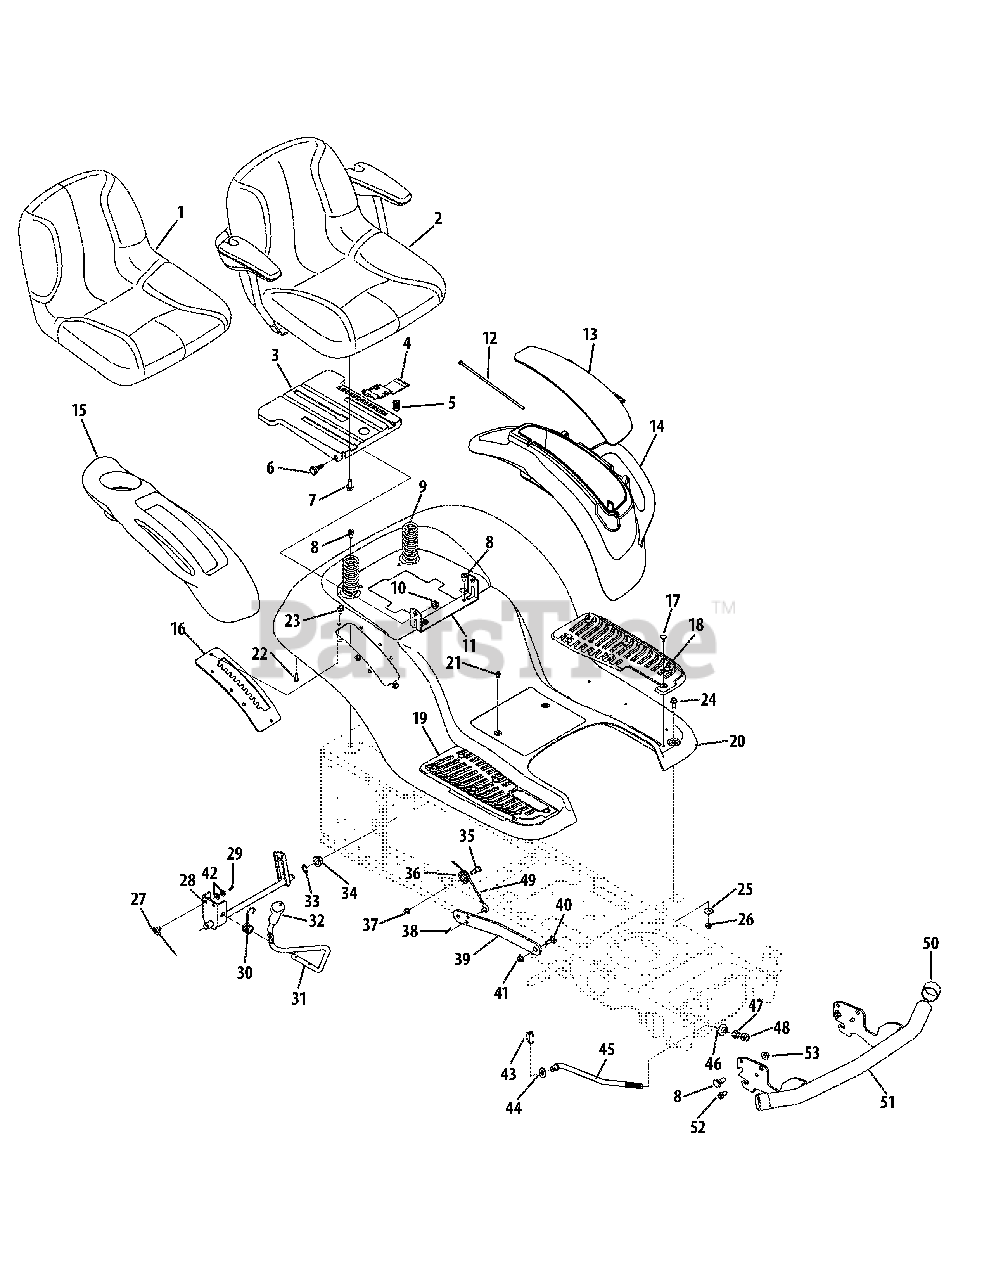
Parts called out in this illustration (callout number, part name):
1	High-Back Chair
2	High-Back Chair
2	Screw, 5.16-18 x .750
3	Seat Mounting Bracket
4	Seat Adjustment Lever
5	Compression Spring, .68 x 1.065 x .055
6	Shoulder Screw, 5.16-18 x .437 x .268
7	Hex Flange Bolt, 3.8-16 x .875
8	Hex Washer Screw, 5.16-18 x .750
9	Compression Spring, 1.71 x 3.735 x .238
10	Flange Lock Nut, 5.16-18
11	Seat Pivot Bracket
12	Door Pin LH Pod
13	Fender Cover Door
14	Fender Cover, LH
15	Fender Cover, RH
16	Lift Adjustment Bracket - Electric PTO
17	Ratchet Clip
18	Foot Pad, LH
19	Foot Pad, RH
21	Hex Washer Screw, 1.4-20 x .500
22	Hex Washer Screw, 1.4-15 x .750
23	Hex Washer Screw, 5.16-18 x .750
24	Hex Washer Screw, 5.16-18 x .750
25	Flat Washer, .344 x 1.0 x .063
26	Flange Lock Nut, 5.16-18
27	Lift Cable
28	Lift Shift Assembly SLTX1050
28	Lift Shift Assembly SLTX1054
29	Cotter Pin, .072 x 1.13
30	Torsion Spring
31	Lift Handle
32	Handle Grip
33	E-Type Ring
34	Hex Flange Bearing
35	Shoulder Screw, 5.16-18 x .437 x .470
36	Cable Roller Pulley
37	Flange Lock Nut, 5.16-18
38	Bow-Tie Cotter Pin
39	Lift Arm
40	Shoulder Bolt, 3.8-16 x .500 x .270
41	Flange Lock Nut, 3.8-16
42	Washer, .401 x .870 x .063
44	Flat Washer, 1.2 x 1.25 x .10
45	Deck Lift Rod
46	Bell Washer
47	Hex Nut, 1.2-13
48	Hex Lock Nut, 1.2-13
49	Lift Cable
50	Bumper Cap
51	Universal Bumper Assembly
52	Shoulder Bolt, 3.8-16 x .496 x .336
53	Flange Lock Nut, 3.8-16
